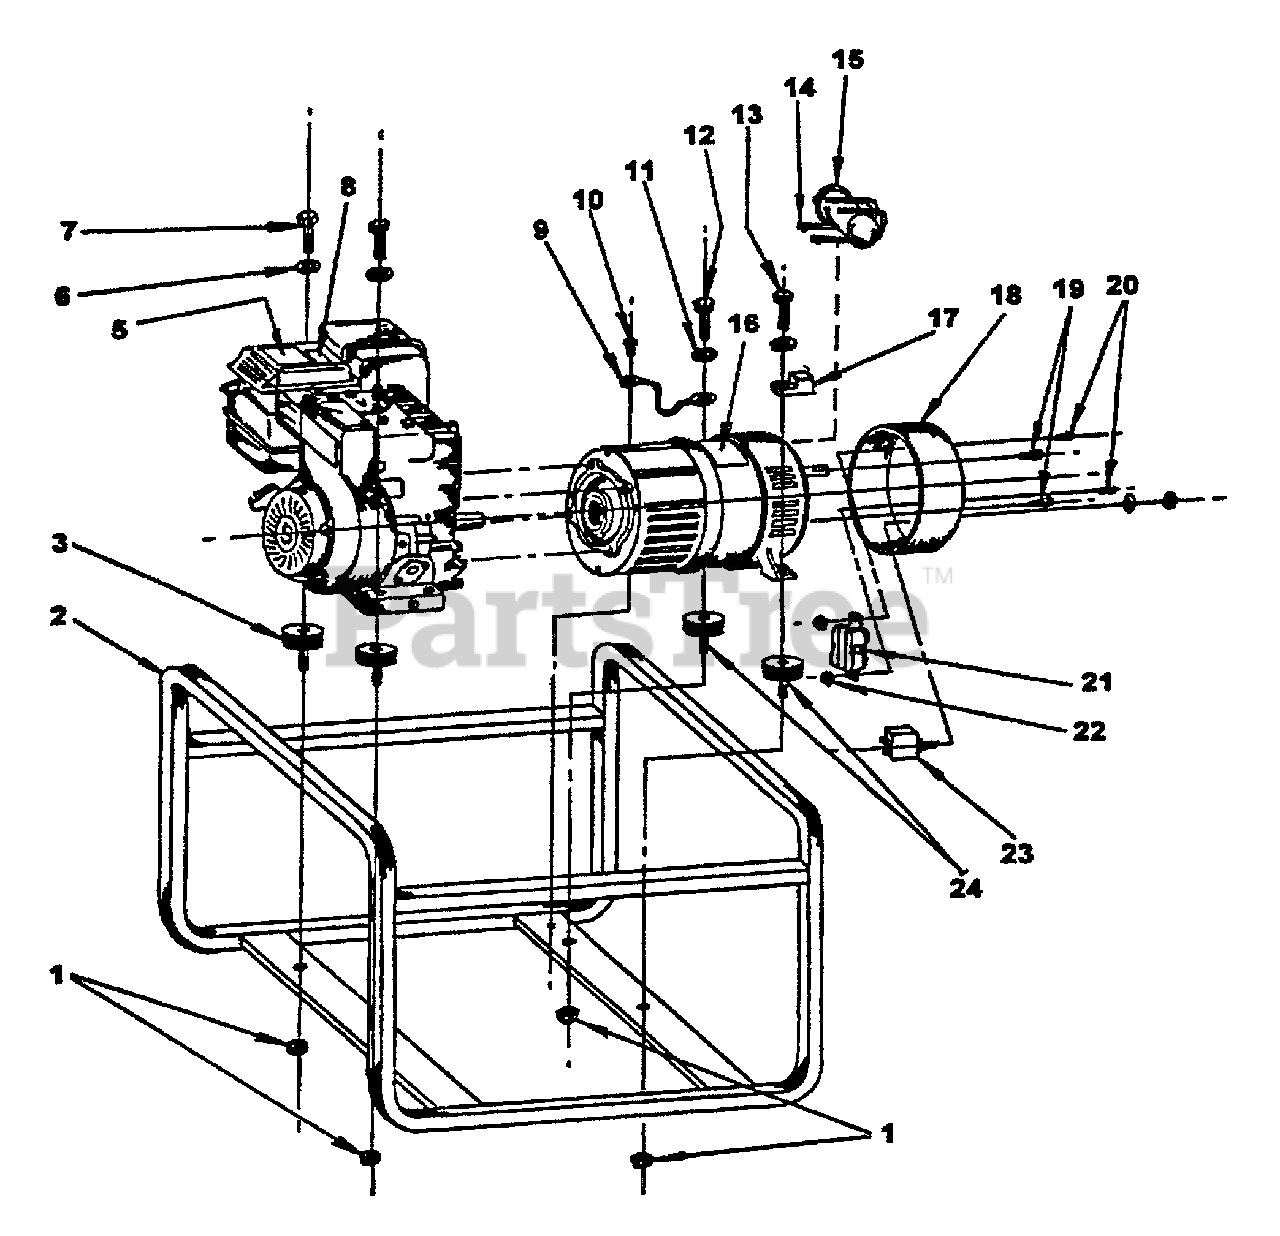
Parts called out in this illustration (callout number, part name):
1	LOCKNUT - 5/16-18
2	FRAME
3	ISOLATOR, VIBRATION
5	LABEL - SAFETY
6	WASHER, LOCK 5×16
7	BOLT - 5/16-18×1-1/2"
9	LEAD - GROUND
10	SCREW - 10-24
11	WASHER, LOCK 5×16
12	5/16-18×5/8 HHS
13	5/16-18×7/8 HHS
14	TIE, CABLE
15	CAPACITOR - 50UF 370V
16	LABEL - MODEL EG-1800
17	LUG, GROUND - 1/0-14 CU/AL
18	PANEL, END
19	SCREW - 10-24 -- SLOT HEAD
20	8-32×3/8 RHS
21	DUPLEX, 15A/125V
22	NUT - 8-32 -- KEPS
23	BREAKER, CIRCUIT - 15A/250V
24	ISOLATOR, VIBRATION
